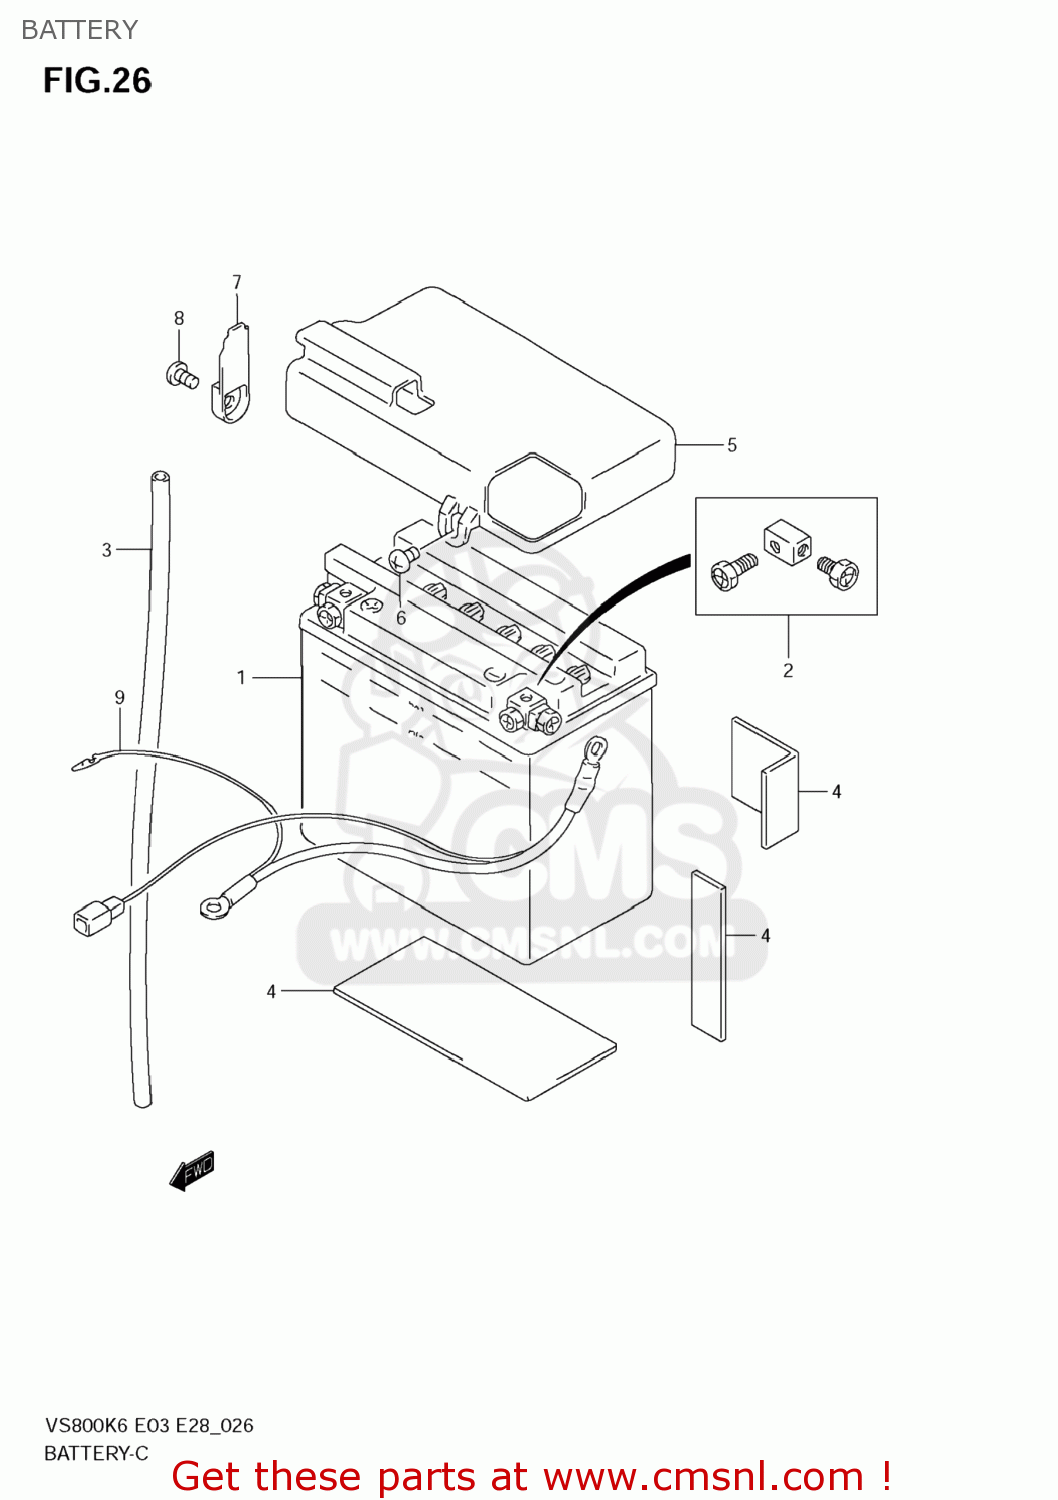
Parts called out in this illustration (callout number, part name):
1	BATTERY ASSY (12V)
2	BOLT SET,BATTERY TERMINAL
3	HOSE,BATTERY EXHAUST(L:780)
4	PROTECTOR(170X95X3.0)
5	COVER,BATTERY UPR
6	SCREW
7	COVER,BATTERY TERMINAL
8	SCREW
9	WIRE,BATTERY MINUS LEAD
